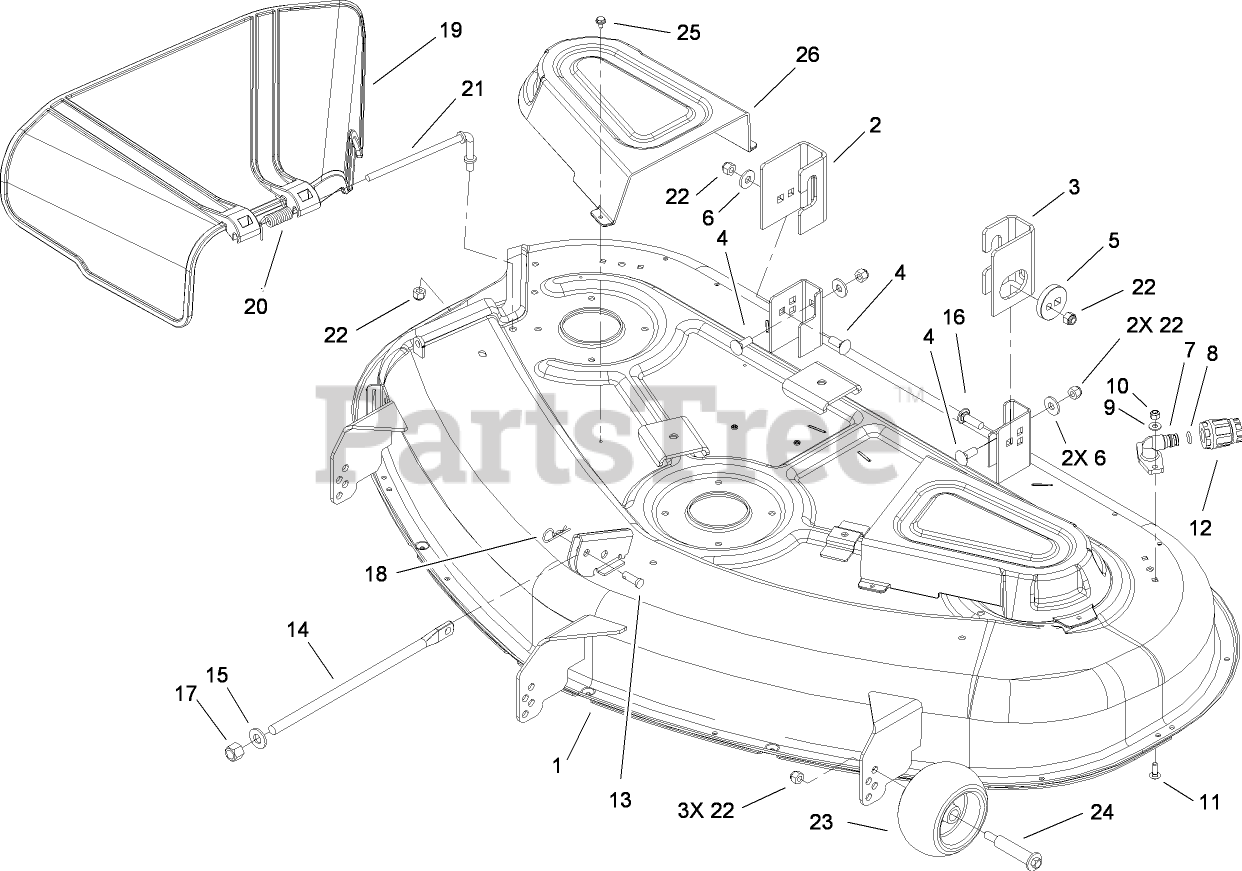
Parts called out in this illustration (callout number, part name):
2	BRACKET-HANGER, RIGHT REAR
3	BRACKET-HANGER, LEFT REAR
4	BOLT-CARR
5	ECCENTRIC
6	WASHER-HARDENED
8	O-RING
9	WASHER-FLAT
10	NUT-LOCK, NI
11	BOLT-CARR
12	CONNECTOR-HOSE
13	PIN-CLEVIS
14	ROD-LIFT
15	WASHER-THRUST
16	SCREW-CARR
17	NUT-LOCK, NI
18	PIN-HAIR
19	DEFLECTOR
20	SPRING-TORSION
21	ROD-PIVOT
22	NUT-LOCK, NI
23	ROLLER-SCALP, ANTI
24	BOLT-SHOULDER
25	SCREW-HWHTF
26	COVER-BELT
